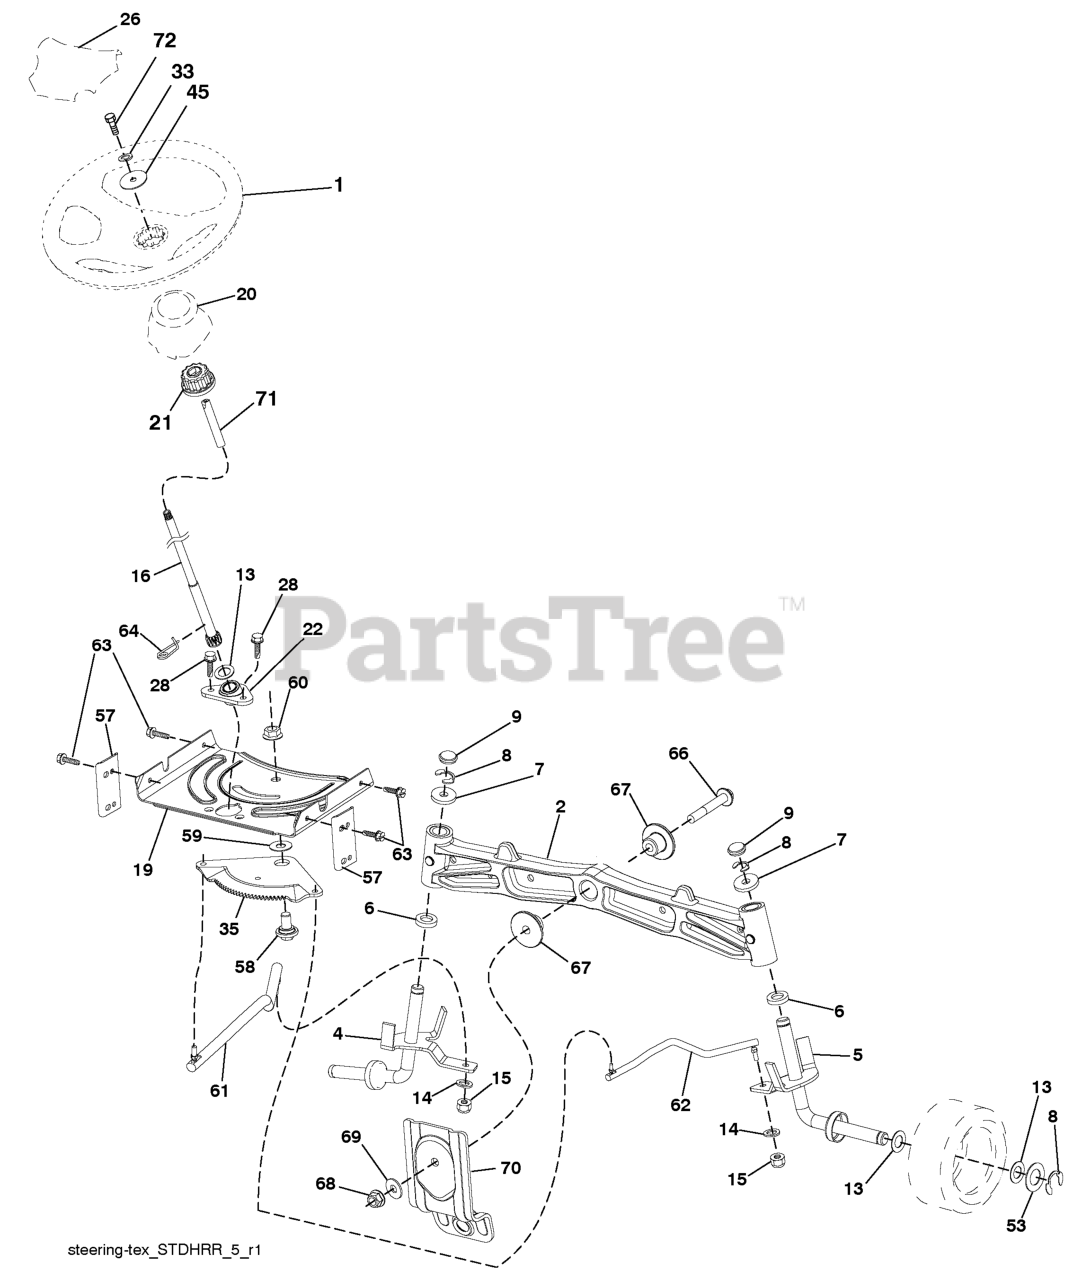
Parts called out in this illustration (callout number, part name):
1	WHEEL STEERING
2	AXLE.CAST.IRON
4	SPINDLE.WELDED.LH.15"TEX
5	SPINDLE.WELDED.RH.15"T
6	THRUST WASHER
9	CAP.SPINDLE.BLACK
14	WASHER, LOCK 3/8
15	NUT CROWNLOCK 3/8-24
16	SHAFT.STEER.3/4.NON-PLATED.TEX
19	PLATE.STEER.DDL.NLT/NG
20	BOOT, STEERING
21	ADAPTER, WHEEL STNG..
22	STEERING.SUPT.LOWER.
26	RP INSERT.CAP.WHL.STRG.HUSQ.
28	SCREW, 3/8-16X3/4
33	WASHER.LOCK.HVY.HLCL.SPR.5/16
35	GEAR.SECTOR.PLATE.DDL.
45	WASHER.11/32
53	WASHER.HARDENED
57	BRACKET.UPSTOP.TEX
58	BOLT.SHOULDER.SECTOR.P
59	WASHER.THURST.SECTOR.S
60	NUT FLANGE LOCK 5/8-11
61	DRAGLINK.LH.BALLSTUD.D
62	DRAGLINK.RH.BALLSTUD.D
63	SCREW
64	RETAINER.CLIP.SPRING.S
66	BOLT HEX FGHD 7/16-14 X 3 SERR
67	BUSHING.PM.FRONT AXLE
68	NUT.LOCK.FLANGE.7/16
69	WASHER.1.5X.505X.118
70	BRKT.DECK.SUSPENSION.F
71	SHAFT.EXTEN.STRG.SPLINE
72	BOLT 5/16-18 X 4 W/PATCH
